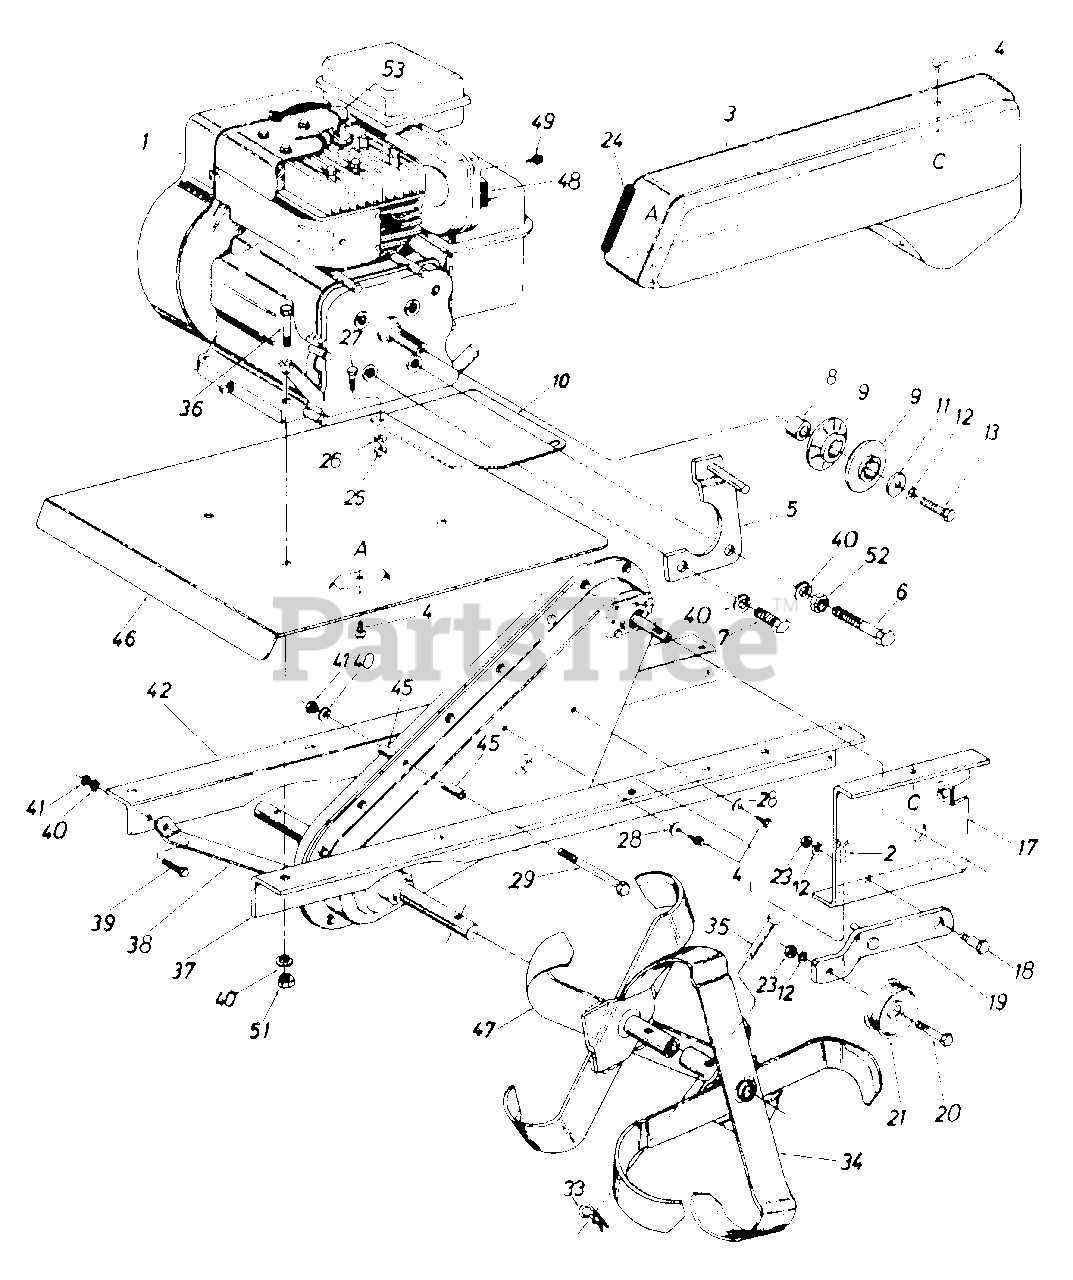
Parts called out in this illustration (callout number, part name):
1	Engine
2	Hex Self-Tap Scr. 5/16-24 x .5
3	Belt Cover
4	Hex Self-Tap Scr. 1/4-20 x .5
5	Belt Keeper Brkt. Ass'y.
6	Hex Bolt 5/16-24 x 2.25n Lg. (Grade 5)
7	Hex Bolt 5/16-24 x .62 Lg. (Grade 5)
8	Spacer
9	Pulley Half
10	Tine Shield Extension
11	Fl-Wash. 3/8 I.D. x 1.25"
12	L-Wash. 818n I.D.
13	Hex Bolt 3/8-24 x 1.00 Lg.
17	Idler Mounting Brkt.
18	Shld. Bolt
19	Idler Bracket Ass'y.
20	Hex Bolt 3/8-16 x 1.5 Lg.
21	Idler Pulley
23	Hex Jam Nut 3/8-16 Thd.
24	Trim Strip-3"
25	Hex Nut 1/4-20 Thd.
26	L-Wash. 1/4" I.D.
27	Hex Bolt 1/4-20 x .62 Lg.
28	Bell-Wash. .26 I.D. x .75 O.D.
29	Hex Bolt 5/16-18 x 3" Lg.
33	Hairpin Cotter
34	See Tine Chart
35	Clevis Pin
36	Hex Bolt 5/16-18 x 1.5" Lg.
37	Frame Rail-L.H.
38	Front Brace Brkt.
39	Hex Bolt 5/16-18 x .75" Lg.
40	L-Wash. 5/16" I.D.
41	Hex Cent. L-Nut 5/1618 Thd.
42	Frame Rail-R.H.
45	Spacer
46	Tine Shield
49	Hex Self-Tap Scr. #8-32 x .38" Lg.
51	Hex Nut 5/16-18 Thd.
52	Hex Nut 5/16-24 Thd.
53	Spark Plug Boot
